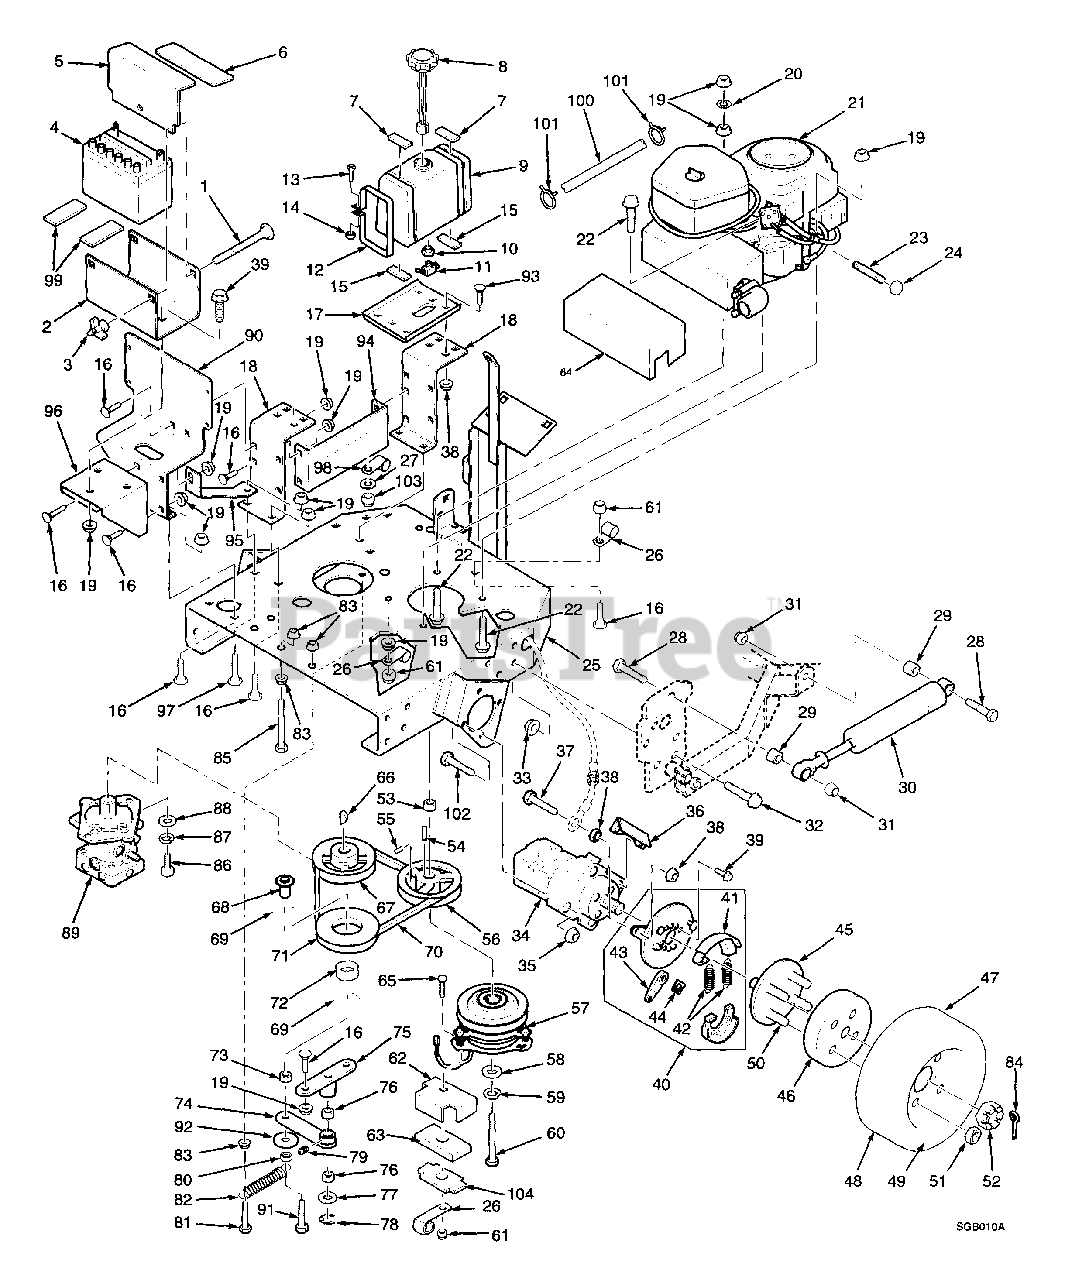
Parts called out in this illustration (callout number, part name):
1	Carriage Bolt, 1/4-20 x 6"
2	Battery Box
3	Nut, Wing 1/4-20
4	Battery
5	Battery Cover
6	Insulation, Battery Cover
7	Pad, Fuel Tank Strap
8	Cap, Fuel Tank
9	Fuel Tank Assy.
10	Bushing, Fuel Tank Valve
11	Fuel Shut Off Valve
12	Strap, Fuel Tank
13	Phil RDHD Machine Screw 1/4-20 x 2"
14	Hex Nut, 1/4-20
15	Pad, Fuel Tank Support
16	Carriage Bolt, 5/16-18 x 3/4"
17	Support, Fuel Tank
18	Bracket, Fuel Tank Support
19	Serr. Fl. Hex Nut 5/16-18
20	Lockwasher, 5/16 Int. Tooth
21	Engine, 20 HP Kohler CV
22	Hex Head CPSCR, 5/16-18 x 1-3/4"
23	Oil Drain Extension
24	Cap, Oil Drain Plug
25	Engine Deck
26	Wire Loom, .50 I.D.
27	Washer, 1/4 (.312 x .750 x .065)
28	Bolt, Hex Head 1/2-13 x 2"
29	Sleeve, Shock Absorber Mount
30	Shock Absorber
31	Hex Locknut, Elastic Stop 1/2-13
32	Serr, Fl Hex Head CPSCR, 7/16-14 x 1"
33	Serr. Fl. Hex Nut, 7/16-14
34	Motor - White
35	Lockwasher, 1/2"
36	Anchor, Brake
37	Bolt, Hex Head 1/4-20 x 1-1/4"
38	Serr. Fl. Hex Nut, 1/4-20
39	Serr. Fl. Hex Head CPSCR, 5/16-18 x.75"
40	Parking Brake Assembly
41	Brake Pads - Pair
42	Springs - Pair
43	Actuating Arm
45	Hub Assembly
46	Brake Drum
47	Rim and Tire Assembly
48	Tire 20 x 10 x 10, 4 Ply
49	Rim Only
50	Bolt, Hub
51	Wheel Nut
52	Castle Nut, 1.0-20 UNEF
53	Spacer, Clutch
54	Key, 1/4 x 1/4 x 1-1/2"
55	Hex Socket Set Screw, 5/16-18 x 3/8"
56	Pulley, Engine Pump Drive
57	Clutch, Electric
58	Flatwasher, 7/16 (.469 x 1.75 x .25)
59	Lockwasher, 7/16"
60	Bolt, Hex Head 7/16-20 x 2.75"
61	Hex Locknut, Elastic Stop 5/16-18
62	Backing Plate, Clutch Stop
63	Rubber Pad, Clutch Stop
64	Heatshield, Muffler
65	Bolt, Hex Head 5/16-18 x 1-3/4"
66	Key, Woodruff 3/16 x 5/8"
67	Pulley, Pump Input
68	Sleeve, Idler
69	Ring, Retaining, 1-9/16 Internal
70	Belt, Pump Drive
71	Pulley, Idler-Traction Drive
72	Bearing, Idler Pulley
73	Spacer, Idler
74	Pump Idler Arm
75	Idler Pivot Base
76	Bushing, Oil lube
77	Flatwasher, 3/4"
78	Ring, Retaining, 3/4" Ext "E"
79	Grease Fitting
80	Hex Nut, Jam 3/8-16
81	Bolt, Hex Head 3/8-16 x 3-1/4"
82	Spring, Pump Drive Idler
83	Serr. Fl. Hex Nut, 3/8-16
84	Cotter Pin, 5/32 x 1.50"
85	Bolt, Hex Head 3/8-16 x 5"
86	Socket Head CPSCR, 1/2-13 x 1-1/4"
87	Lockwasher, 1/2"
88	Flatwasher, 1/2 (.516 x .938 x .105)
89	Pump, Sundstrand
90	Bracket, Oil Tank Support
91	Bolt, Hex Head 3/8-16 x 1-3/4"
92	Washer 2" OD, 3/8 ID, 16 Ga.
93	Carriage Bolt, 1/4-20 x 3/4"
94	Guard, Pulley
95	Gusset, Battery Box
96	Support, Battery Box
97	Carriage Bolt, 5/16-18 x 1"
98	Wire Loom, .75" ID
99	Rubber Pad
100	Fuel Hose
101	Clamp, Fuel Hose
102	Bolt, 1/2-13 x 2.50"
103	Nut, 1/4-20 Elastic Stop
104	Plate, Backing
